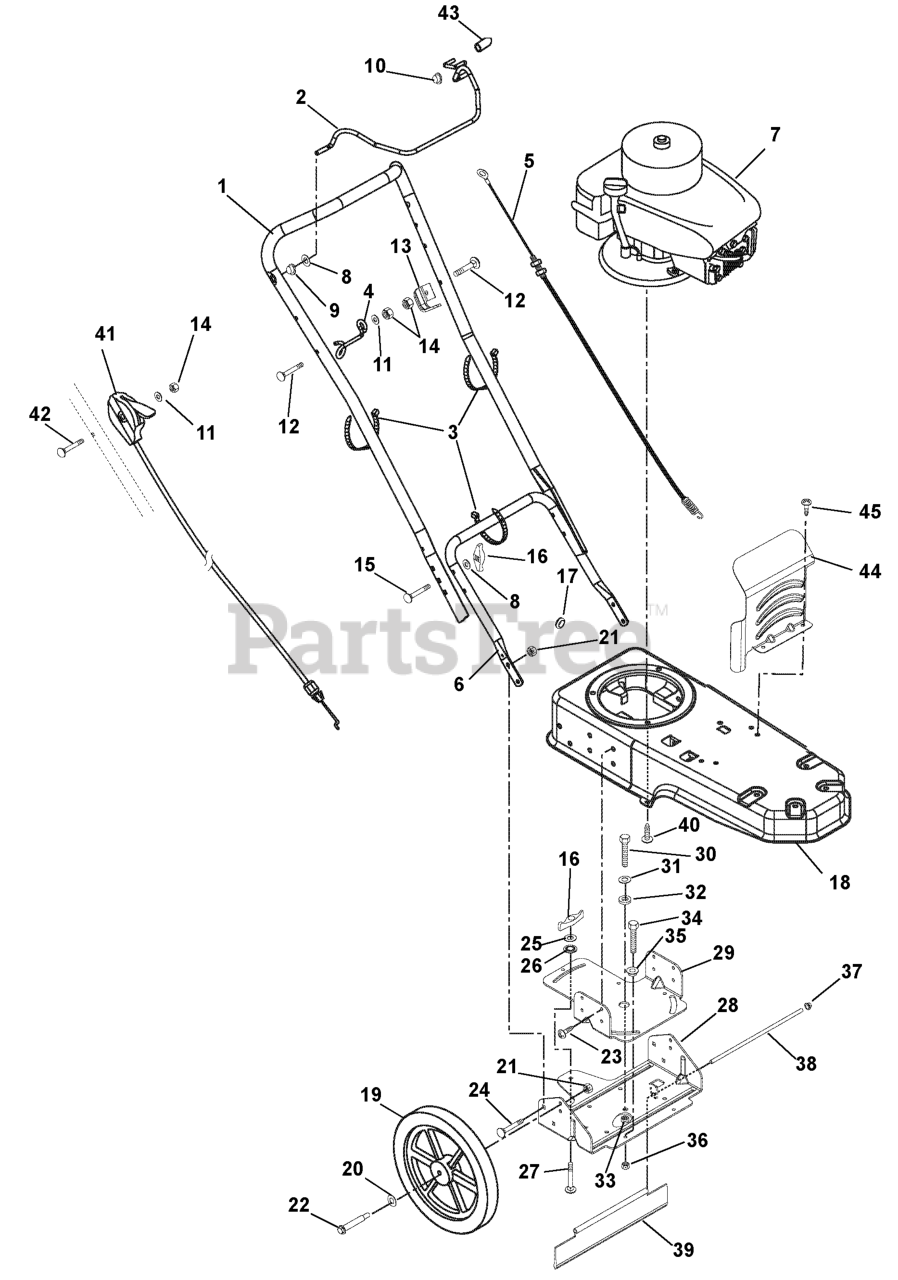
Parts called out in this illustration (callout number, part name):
1	HANDLEBAR - UPPER
2	BAIL SS LF
3	CABLE TIE LG 5-1/2
4	GUIDE - PULLCORD
5	CABLE - CONTROL
6	HANDLEBAR - LOWER
7	KIT - 6 HP TEC ENGINE-ARIENS
8	@WSHR-FL-STL.344X.688X.065YWZC
9	BSHG-FLG .325X.444X.440X.560
10	PUSH NUT, .25
11	@WSHR-FL-STL.281X.62X.065 YWZC
12	BLT-RDHDXLSQNK.25-20X1.25 G5ZC
13	ANCHOR - CABLE
14	@NUT-LK-CTR .25-20 YWZC
15	BLT-RDHDSQNKFT .31-18X2.0 G5YZ
16	KNOB - WING .312-18 UNC
17	GROMMET .50 ID
18	FRAME - TRIMMER
19	WHEEL 14 X 1.75 X .50
20	WSHR-FL-STL .52X.827X.062 YWZC
21	@NUT-LK-CTR .38-16 YWZC
22	BLT-SHLDR .38-16X2.50 HWH G5
23	@SCR-TAP .38-16X.75 HWH TR YWZ
24	@BLT-RDHDSQNK .38-16X.75 G5YZ
25	@WSHR-FL-STL.38X.875X.083 YWZC
26	NUT-PUSH .312
27	@BLT-RDHDSQNK .31-18X1.00 G5YZ
28	BRACKET - AXLE - SWIVEL
29	BASE - SWIVEL
30	@BLT-HEX .50-13X1.00 GR5 YWZC
31	@WSHR-FL-STL.563X1.38X.109YWZC
32	SPACER .531 X 1.00 X .225
33	@NUT-LK-CTR .50-13 YWZC
34	@BLT-HEX .31-18X1.00 GR5 YWZC
35	BSHG-FLG .32X.500X.344X.880
36	@NUT-LK-CTR .31-18 YWZC
37	NUT-PUSH .312 DIA. PAL
39	GUARD - REAR - SWIVEL
40	@SCR-TAP .38-16X1.00 HWH TR YZ
41	CONTROL - THROTTLE
42	BLT-RDHDXLSQNK .25-20X2.0 G5YZ
43	CAP, VINYL, .25 ID
44	GUARD - ENGINE
45	@SCR-TAP .38-16X.50 HWH TR YWZ
